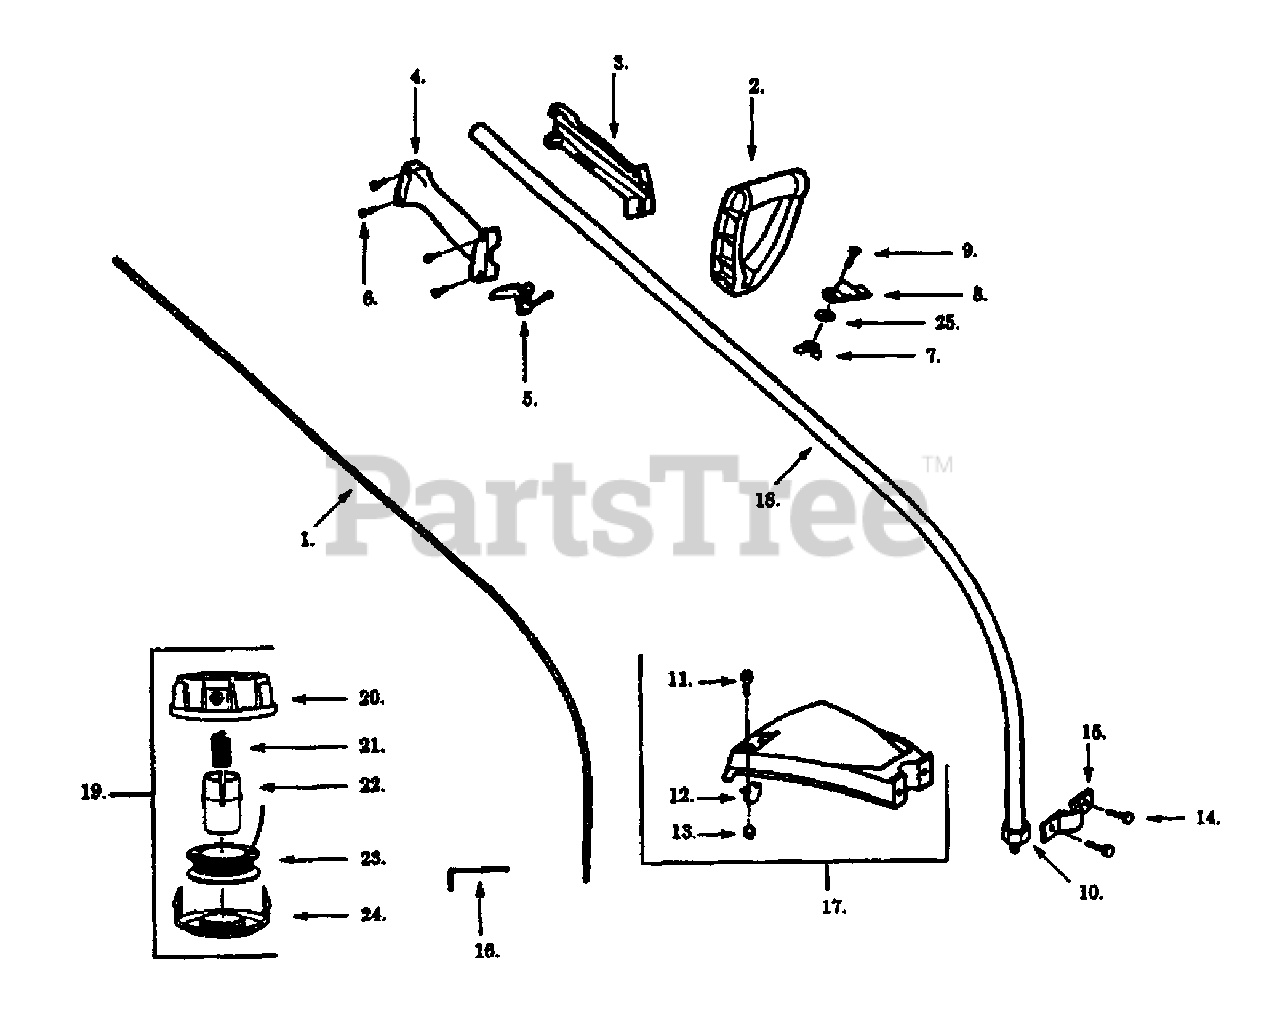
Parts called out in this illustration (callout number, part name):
1	Drive Shaft-46"
2	D" Handle
3	Throttle Hag. (Left)
4	Throttle Hag. (Right)
5	Throttle Lever
6	Screw-Throttle Hag.
7	Wing Nut-Handle
8	Clamp-Handle
9	Bolt-Handle
11	Screw-Line Limiter
12	Line Limiter
13	Lockout-Line Limiter
14	Screw-Shield
15	Shield Bracket
16	Hex Wrench (5/32)
17	Shield Kit Ass'y
18	Drive Shaft Hag.
19	Cutting Head Ass'y.
20	Hub Ass'y.
22	Release Button
23	Spool w/Line
25	Washer-Handle
